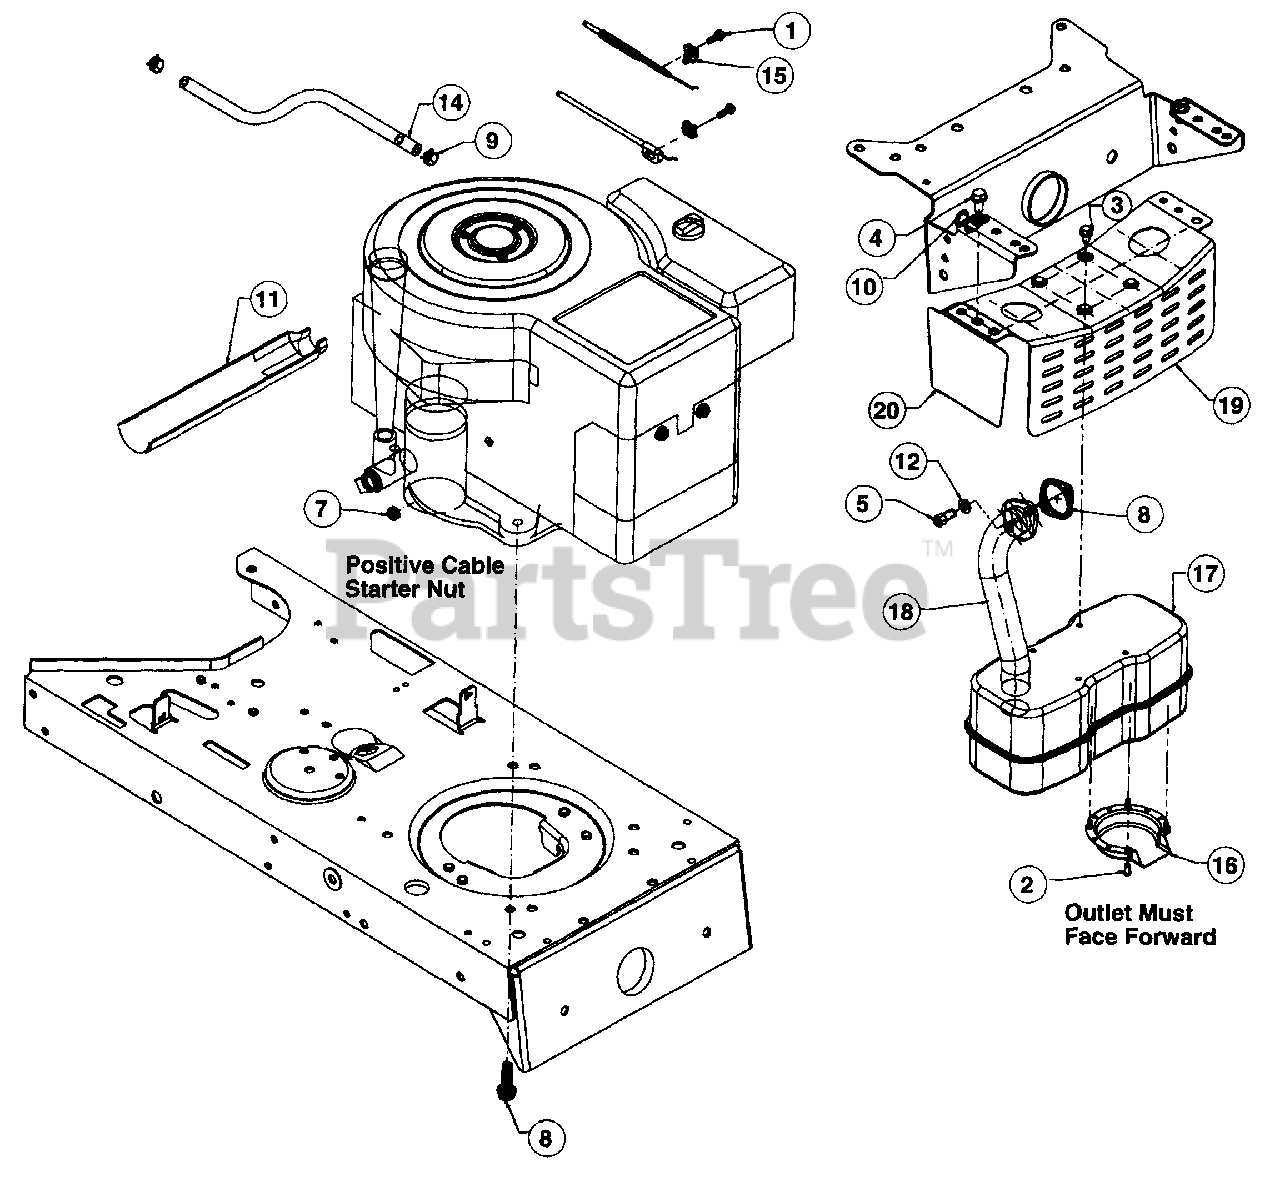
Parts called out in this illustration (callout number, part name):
1	Hex Wash. Scr. #10-32 x .62" Lg.
2	Hex Tap Scr. #8-32 x .38" Lg.
3	Hex Wash. TT-Tap Scr. 1/4-20 x .5" Lg.
4	Hex Wash. TT-Tap Scr. 5/16-18 x .62" Lg.
5	Socket Head Scr. 5/16-18 x .62" Lg.
7	Hex Sems Scr. 1/4-20 Thd.
8	Gasket
11	Oil Drain Sleeve
12	Lock Washer 5/16" I.D.
14	Fuel Line 12" Lg.
15	Casing Clamp
16	Muffler Deflector
17	Muffler
18	Exhaust Pipe
20	Shield Brkt.
